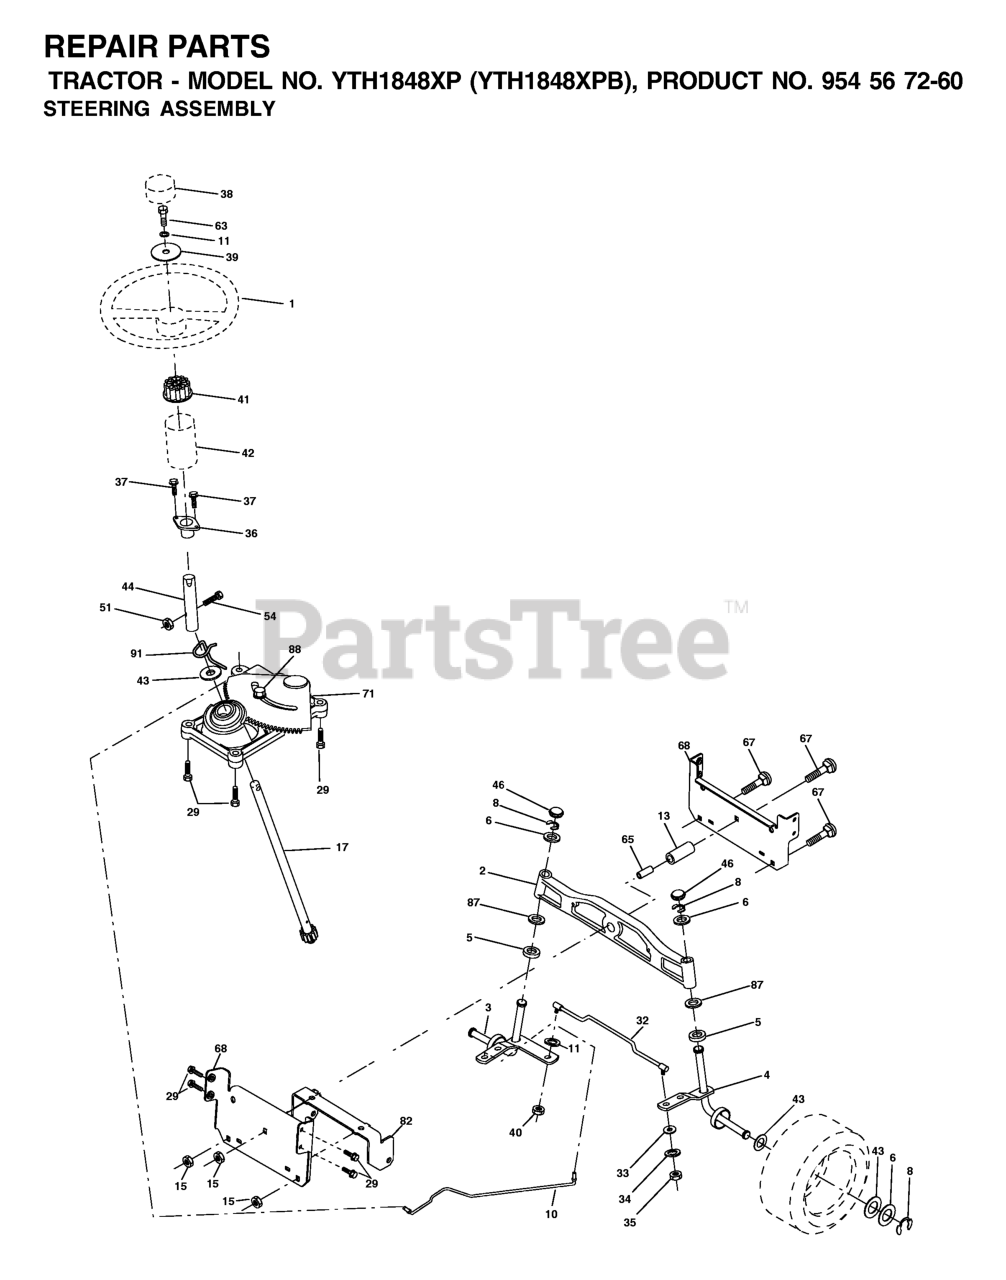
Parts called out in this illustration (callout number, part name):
1	STEERING WHEEL
2	AXLE ASM
3	SPINDLE.ASM.LH.15"TIRES
4	SPINDLE.ASM.RH.15"TIRES
5	THRUST WASHER
10	DRAGLINK.15".TIRES.2001
11	WASHER, LOCK 3/8
13	TUBE, PIVOT AXLE
15	NUT
17	SHAFT ASM
29	SCREW 3/8-16X3/4
32	ROD.ASM.TIE.BALL.JOINT.NOVAN
33	WASHER M
34	WASHER.LOCK.HVY.HLCL.SPR.5/16
35	NUT, CROWNLOCK
36	BUSHING, STEERING
37	SCREW.TT.#10-32X.5.3/8.FLANGE
38	CAP.WHEEL.STEERING.GREY
39	Washer 13/32 x 1-1/20 x 11 Gauge
40	GRIPCO NUT
41	STEERING WHEEL ADAPTOR
42	BOOT STEERING
44	EXT SHAFT STEERING
46	CAP.SPINDLE.BLACK
51	NUT.71038.31-18.HEX.NYLOCK
54	BOLT.5/16-18X1-1/4 FULL.THREAD
65	SPACER BRACE AXLE
67	BOLT
68	BRACE.AXLE.15"TIRES
71	STEERING ASM
82	BRACKET
87	WASHER, FLAT .781 X 1 1/2"
88	BOLT, SHOULDER 7/16-20
91	CLIP.STEERING
